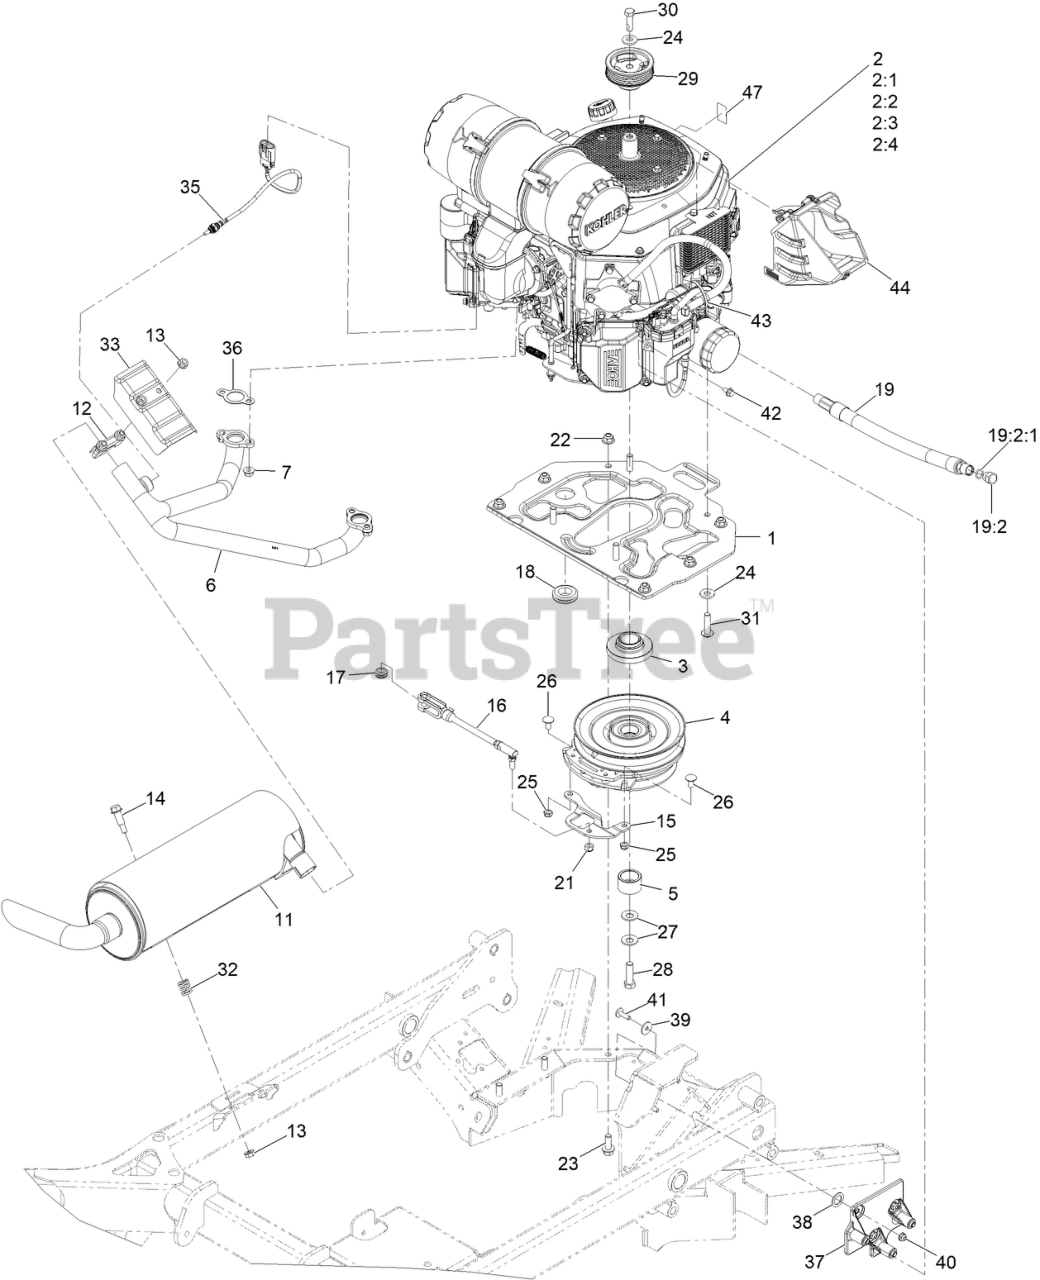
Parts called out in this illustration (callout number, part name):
1	PLATE, ENGINE
2	Engine, Kohler Cv650 EFI
2:1	Kohler 52 050 02-S Engine Oil Filter
2:2	Kohler 25 083 01-S Engine Air Filter
2:3	Kohler 25 083 04-S Safety Filter
2:4	Kohler 25 050 42-S Fuel Filter
3	SPACER, CLUTCH 1.13
5	SPACER, CLUTCH
6	HEADER, KOHLER
7	NUT-FLANGE
11	MUFFLER, 5
12	CLAMP-MUFFLER
14	Bolt-Shoulder
15	STRAP, CLUTCH
16	ASM, CLUTCH ANCHOR
17	GROMMET
18	GROMMET
19	OIL DRAIN HOSE ASM
19:2	PLUG-HH
19:2:1	O-RING
21	NUT-LOCK
22	NUT-HF, NI
23	SCREW-HHF 3/8-16 X 1
24	WASHER-BELLEVILLE
25	NUT-LOCK, NI
26	SCREW-CARR
27	WASHER-SPRING
28	SCREW-HH 7/16-20 X 1 1/2 W/LOCTITE
29	PULLEY, CRANK
30	Screw-HH, Patch
31	SCREW-BHTF
32	SPRING, COMPRESSION
33	SHIELD, HEAT
35	SENSOR, MINI O2
36	GASKET-EXHAUST
37	Bracket-Pump, Fuel
38	Washer-Rubber
41	SCREW-TRUSS
42	SCREW-HHF
44	DUCT, AIR
47	DECAL-10W-50 OIL
